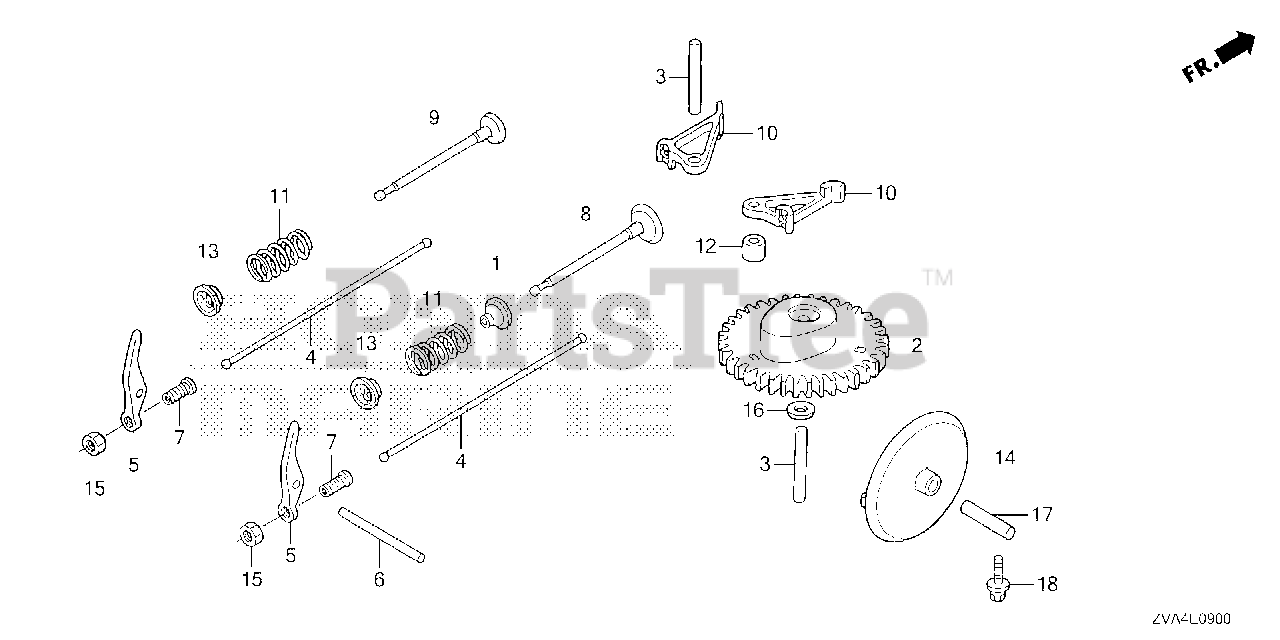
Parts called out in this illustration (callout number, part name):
1	SEAL, VALVE STEM
3	ROLLER (5X29.8)
5	ARM, VALVE ROCKER
6	ROLLER (4X37.8)
7	PIVOT, ROCKER ARM
8	VALVE, IN.
9	VALVE, EX.
10	LIFTER, VALVE
11	SPRING, VALVE
12	COLLAR, LIFTER
13	RETAINER, VALVE SPRING
14	SLINGER, OIL
15	NUT, TAPPET ADJUSTING
16	WASHER (6MM)
17	ROLLER (6X25)
18	BOLT-WASHER (5X16)
